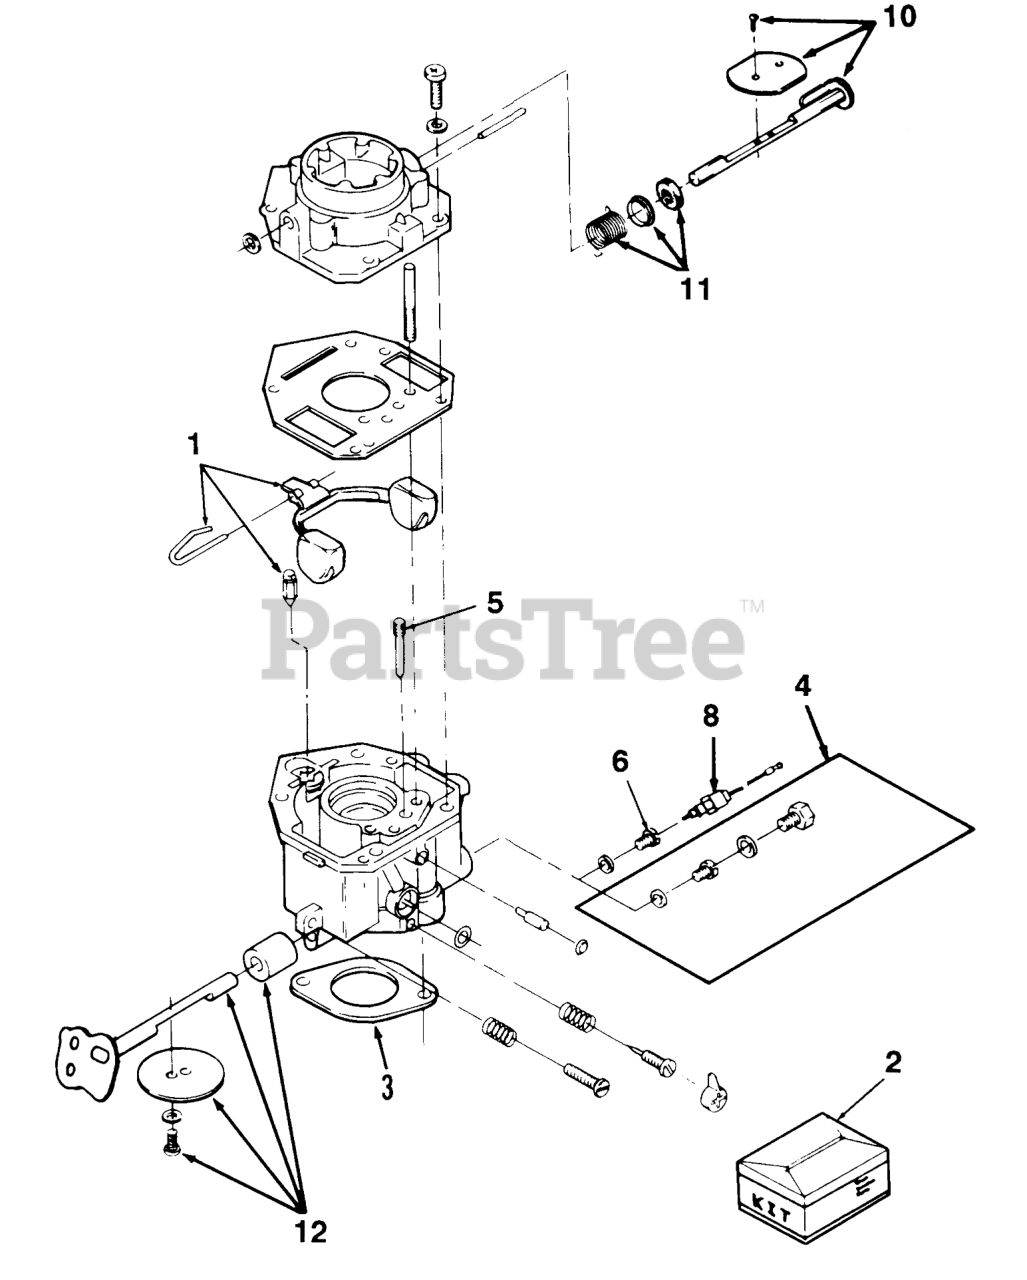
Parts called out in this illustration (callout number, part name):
1	Kit-Float (Incl. Float, Pin, & Valve)
2	Kit-Repair (Incl. Screw & Plug Package, Gasket Package, Float Valve, Idle Adjustment Needle & Spring, Mounting Gaskets, & Idle Limit Cap)
3	GASKET-CARBURETOR
4	JET-FIXED, HIGH ALTITUDE
5	JET-IDLE
6	JET-POWER
8	Solenoid-Fuel Cut-Off (Incl. Gasket)
10	Kit-Choke Shaft (Incl. Choke Valve, Valve Set Screw, & Air Filter)
11	Kit-Choke Lever (Incl. Choke Lever Ring, Choke Spring, & Choke Collar)
12	Kit-Throttle Shaft (Incl. Valve Set Screw, Air Filter, & Throttle Valve)
